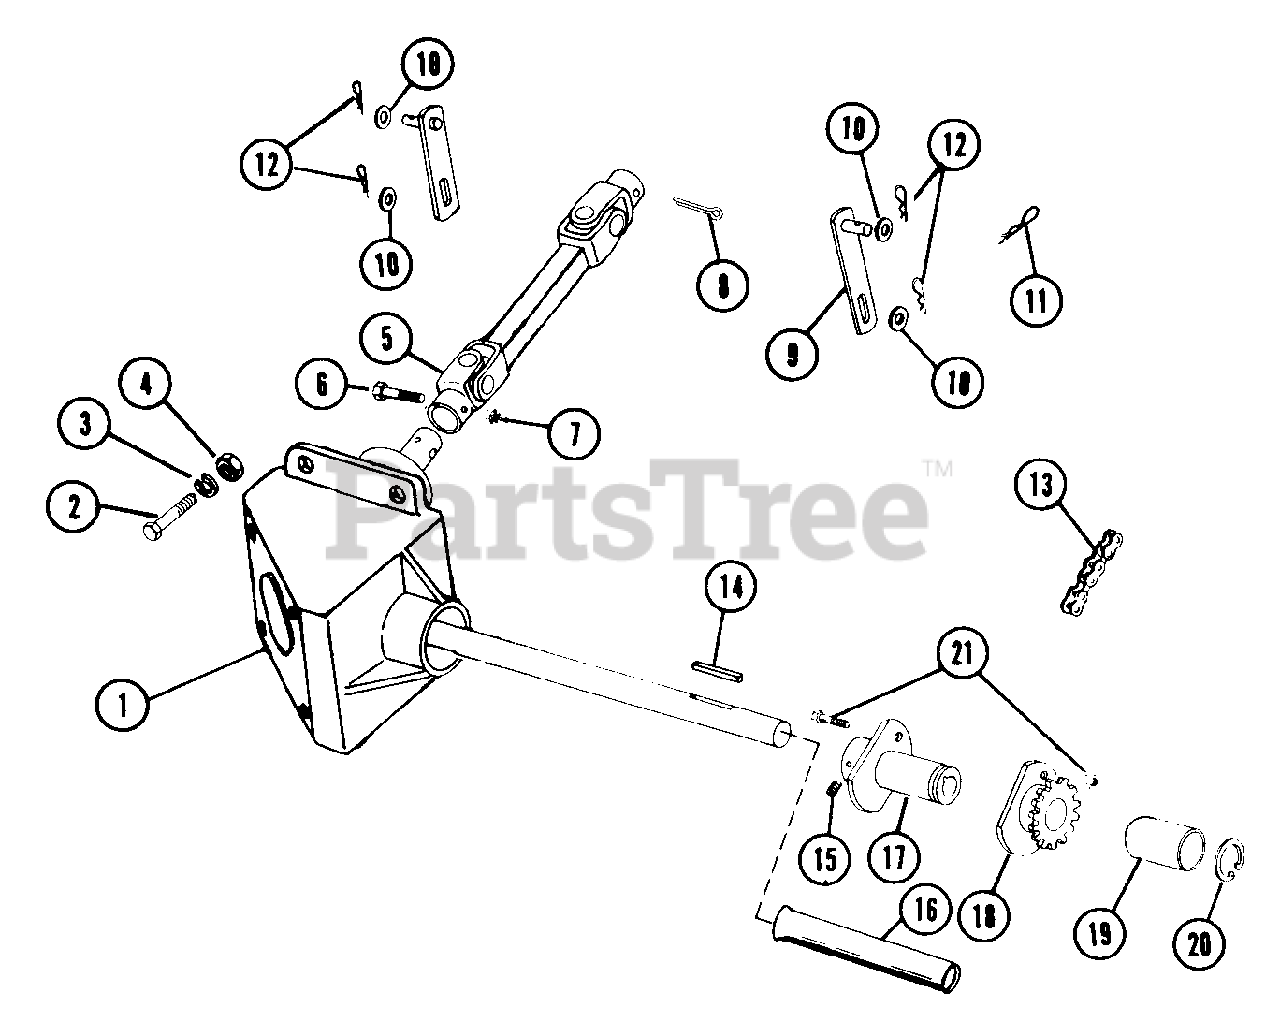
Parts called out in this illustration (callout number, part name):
1	SNOW THROW GEARBOX ASSEMBLY
2	BLT-HEX .38-16X1.25 PL GR5
3	WSHR-LK .375X.094 MED PL
4	NUT-HEX .375-16
5	UNIVERSAL SHAFT ASSEMBLY
6	BLT-HEX .25-20X2.00 PL GR5
7	NUT-LK TOP .250-20 PL
8	PIN-HAIR INT .18X1.18X3.25 PL
9	LIFT STRAP
10	WSHR-FL-STL .531X1.062X.095 PL
11	PIN-HAIR INT .14X.4X2.75
12	PIN-HAIR INT .09X.188 PL
14	KEY-WDRF .188X.75X.313 SAE 9
15	SET SCREW
16	PTO SHIELD
17	SHEAR HUB
18	SPROCKET
19	BSHG-FLG .280X1.870X.750 NY
20	RG-RTNG-EXT 1.125X.050
21	SHEARBOLT & NUT ASSEMBLY
